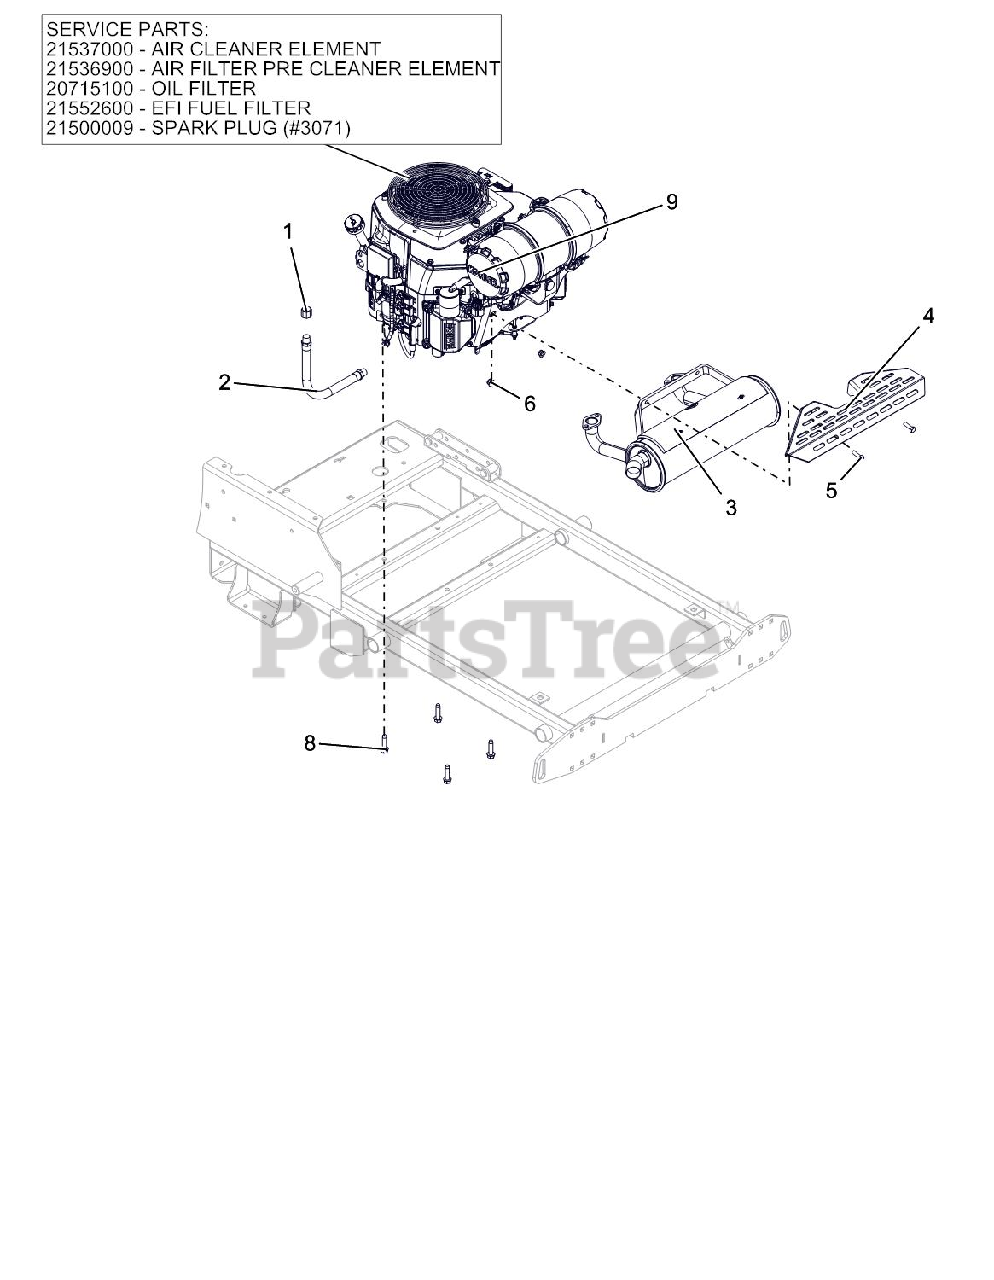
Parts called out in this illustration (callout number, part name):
1	PIPE CAP 3/8 NPT FEMALE
2	HOSE,HYD .38-14-0K M6N0-M6N0
3	MUFFLER, KOHLER EFI PRO-STANCE
4	GUARD, MUFFLER
5	@BLT-HEX .31-18X1.00 GR5 YWZC
6	@NUT-LK-NYL-FLG .31-18 YWZC
8	@SCR-TAP .38-16X1.50 HWH TR YZ
9	ELEMENT, INNER SAFETY
9	ELEMENT, OUTER PRIMARY
9	ENGINE, KOHLER PCV740 EFI LP
9	PLUG, SPARK KOHLER
9	OIL FILTER KOHLER
9	FILTER-FUEL KOHLER PROPANE
